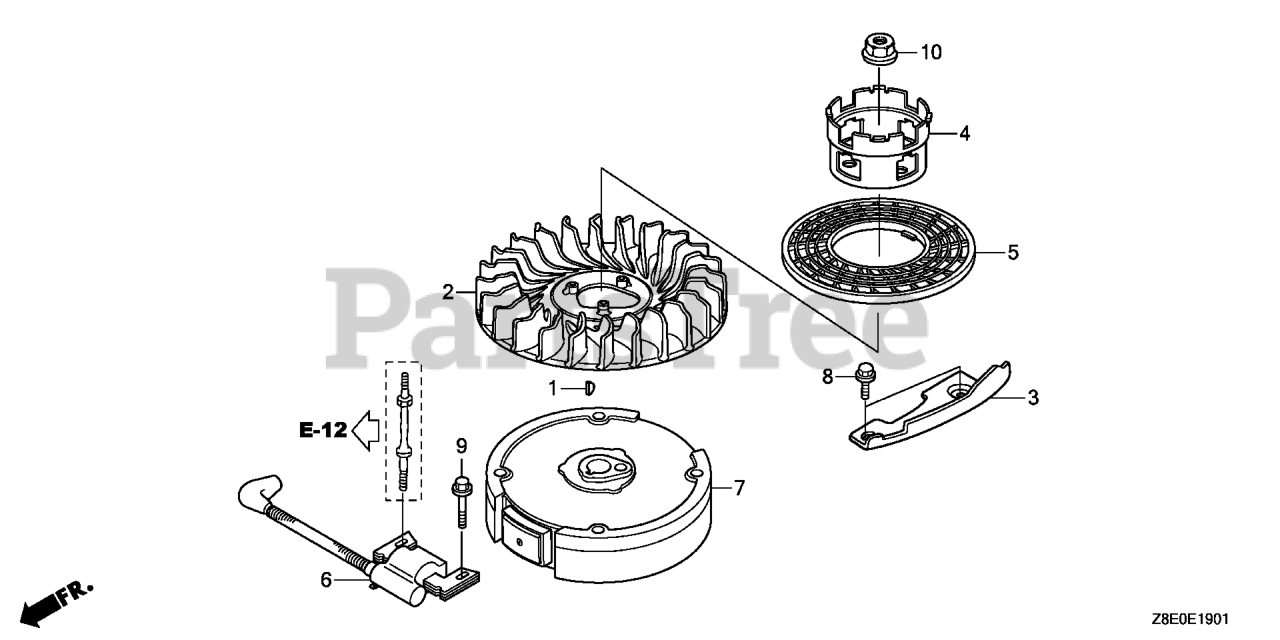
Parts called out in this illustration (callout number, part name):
1	KEY, SPECIAL WOODRUFF (25X18)
2	FAN, COOLING
3	PLATE, SIDE
4	PULLEY, STARTER
5	GRID, SCREEN
6	COIL ASSY., IGNITION (PHELON)
7	FLYWHEEL
8	BOLT, FLANGE (6X12) (CT200)
9	BOLT, FLANGE (6X23)
10	NUT, SPECIAL (14MM)
